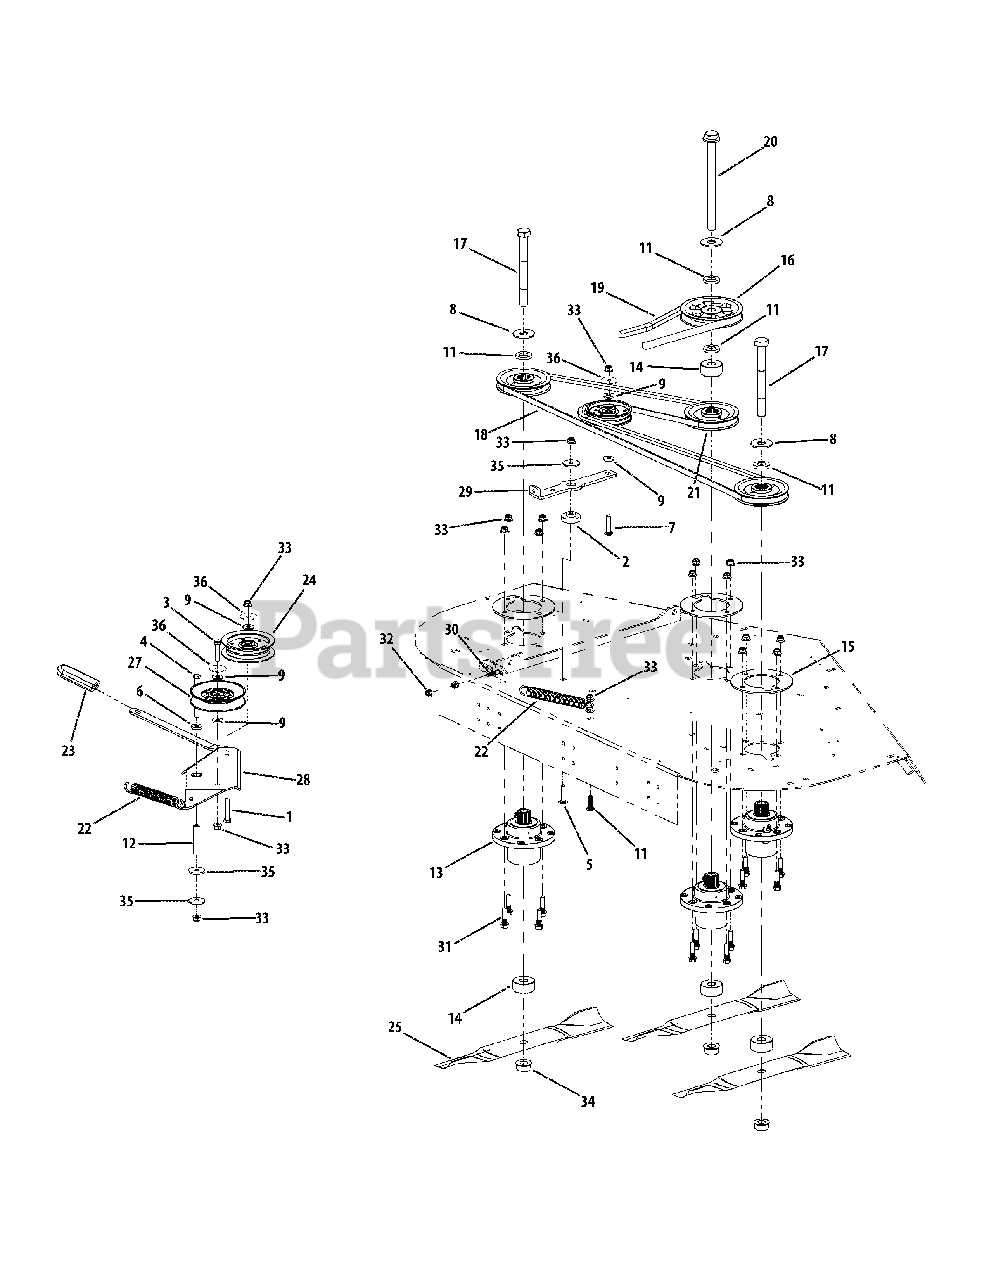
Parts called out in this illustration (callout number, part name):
1	Hex Cap Screw, 3/8-16 x 2.00
2	Shoulder Screw, .854 x .280
3	Hex Cap Screw, 3/8-16 x 1-3/4
4	Hex Cap Screw, 3/8-16, 4.00
5	Carriage Bolt, 3/8-16 x 1-1/2
6	Flat Washer, 3/8
7	Carriage Bolt, 3/8-16, 2.00
8	Flat Washer, .781 ID, 2.00 OD, .105
9	Flat Washer, .406 ID, 1.0 OD, .105
10	Carriage Bolt, 3/8-16 x 1-1/4
11	Spacer, .812 ID x .218 LG
12	Spacer, .39 ID x .625 OD x 2.75
13	Spindle Ass’y, Aluminum Fab Deck
14	Spacer, .760 ID x 2.000 OD x 1.1
15	Plate Support, Cast Alumn. Spindle
16	V Pulley, 5.774 OD
17	Hex Cap Screw, 3/4-16, 7.00
18	V Belt, A Section x 114.3
19	V Belt, B Section x 91.2
20	Hex Cap Screw, 3/4-16, 9.00
21	V Pulley, 5.00 OD
22	Spring Extension, .94 OD x 7.57
23	Idler Tension Handle Grip
24	Idler Pulley, 4.06 OD w/Deep Flange
25	Hi-Lift Blade, 19.0, 0.756
26	Idler Pulley, 4.06 Dia.
27	Idler Pulley, 5.06 Dia.
28	Idler Arm Assembly includes:
28	Bearing
30	Carriage Bolt, 5/16-18 x 1.50
31	Bolt, 3/8-16 x 1.5
32	Nut, 5/16-18, Nylon Flange Lock
33	Nut, 3/8-16, Nylon Flange Lock
34	Flange Hex Nut, 3/4-16
35	Washer, .390 x 1.500 x .134
36	Washer, .406 x 1.92 x .060
